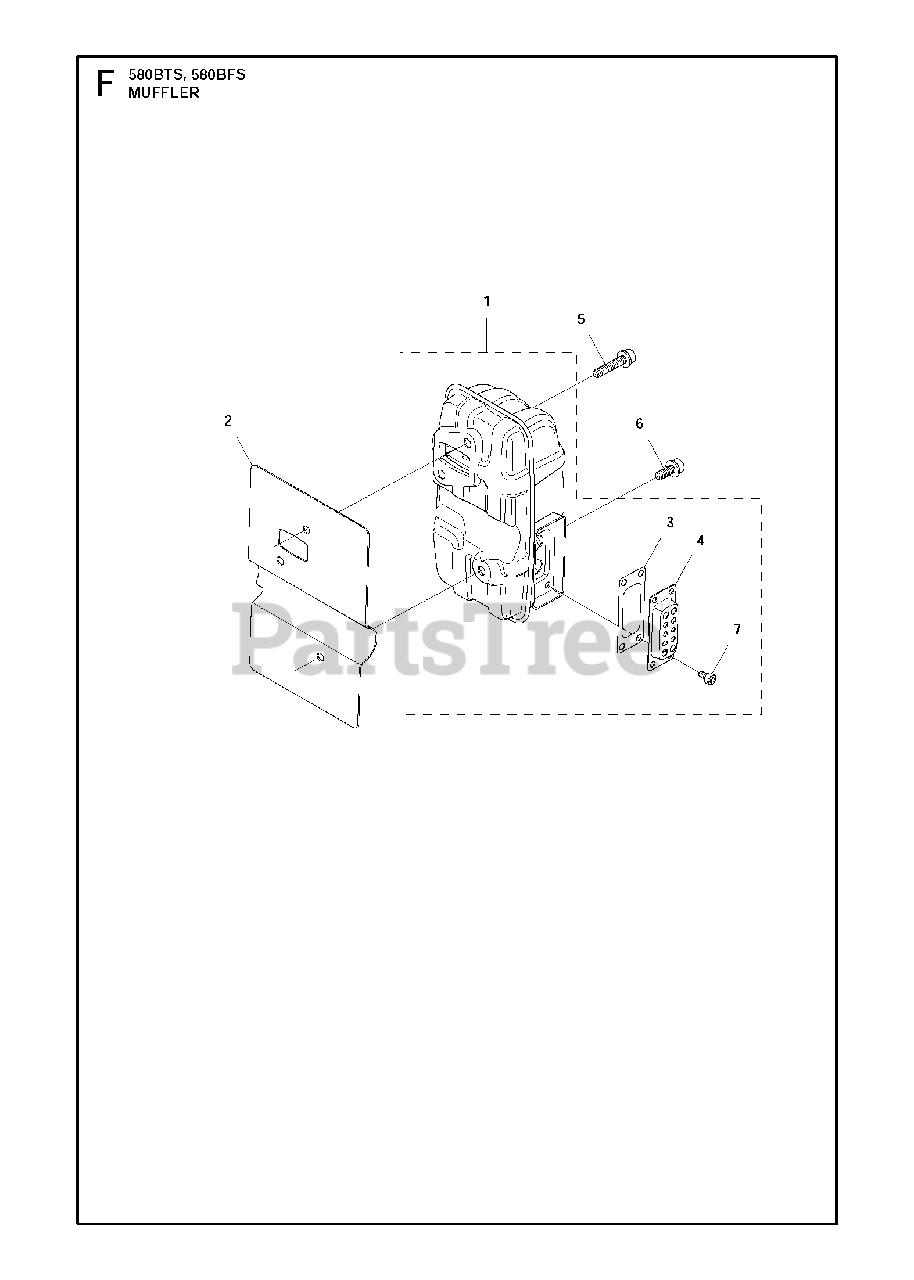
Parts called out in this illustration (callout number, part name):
1	MUFFLER ASSY
3	SPARK ARRESTER
4	DIFFUSOR
7	BOLT
